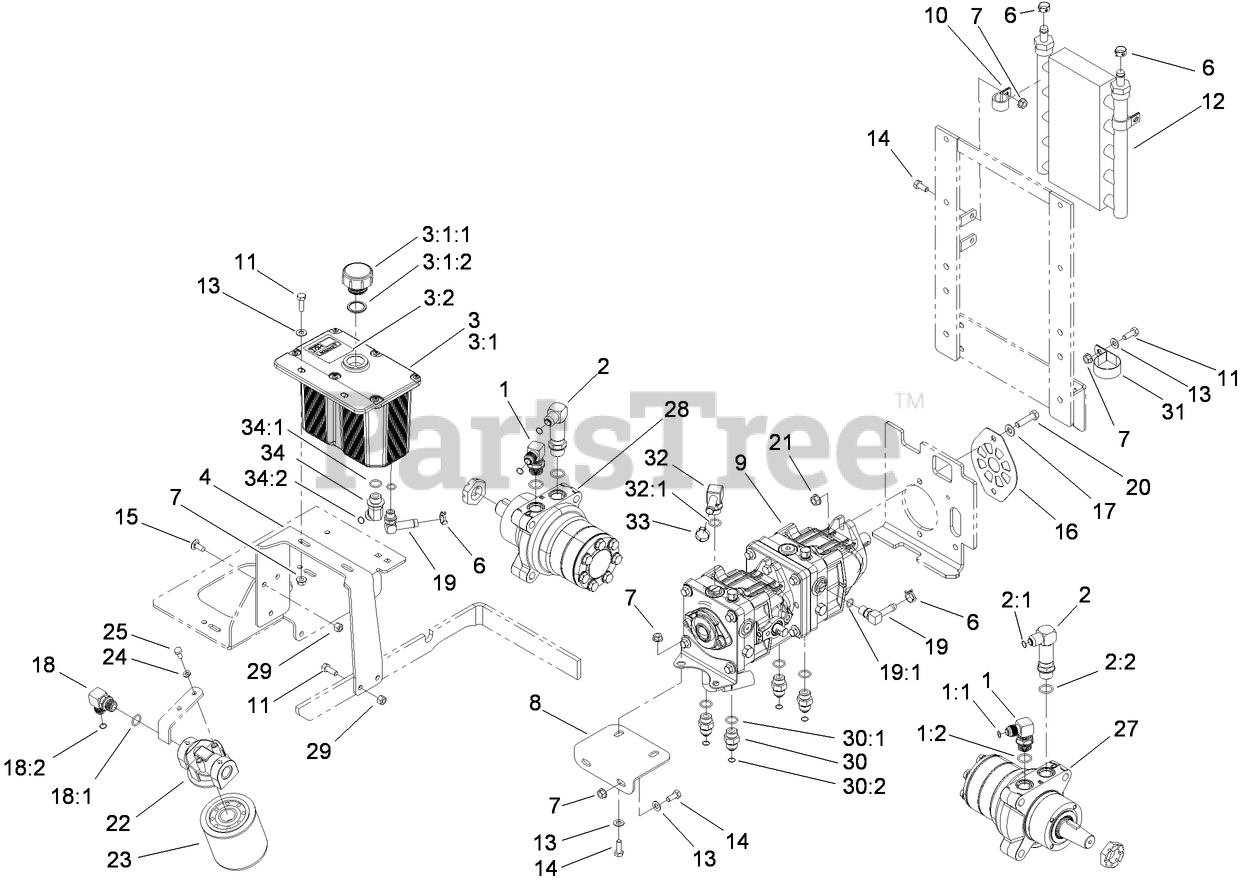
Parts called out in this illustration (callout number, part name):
1	FITTING-HYD, 90 DEG
1:1	O-Ring
1:2	O-RING
2	FITTING-ELBOW-90
2:1	O-Ring
2:2	O-RING
3	HYDRAULIC TANK ASM
3:1	TANK-HYDRAULIC
3:1:1	CAP-RESERVOIR, HYD
3:1:2	GASKET-CAP
3:2	DECAL-WARNING
4	BRACKET-TANK, HYDRAULIC
6	CLAMP-HOSE
7	NUT-HF
8	BRACKET-PUMP, FRONT
9	TANDEM PUMP ASM
10	R-CLAMP
11	SCREW-HH
12	COOLER-OIL, HYDRO
13	WASHER-PLAIN
14	SCREW-HH
15	SCREW-CARR
16	PLATE-SHIELD, PUMP
17	WASHER-FLAT
18	FITTING-90 DEG
18:1	O-RING
18:2	O-Ring
19	FITTING-ELBOW, 90
19:1	O-RING
20	SCREW-HH
21	NUT-HHF, WHIZ
22	HEAD-FILTER
23	CARTRIDGE-FILTER, OIL
24	WASHER-LOCK
25	SCREW-HH
27	HYD MOTOR ASM (CCW)
28	HYD MOTOR ASM (CW)
29	NUT-LOCK, NI
30	FITTING-STRAIGHT
30:1	O-RING
30:2	O-Ring
31	CLAMP-R
32	FITTING-ELBOW, 90 DEG
32:1	O-RING
33	CLAMP-HOSE
34	FITTING-HYD, 45 DEG
34:1	O-RING
34:2	O-Ring
